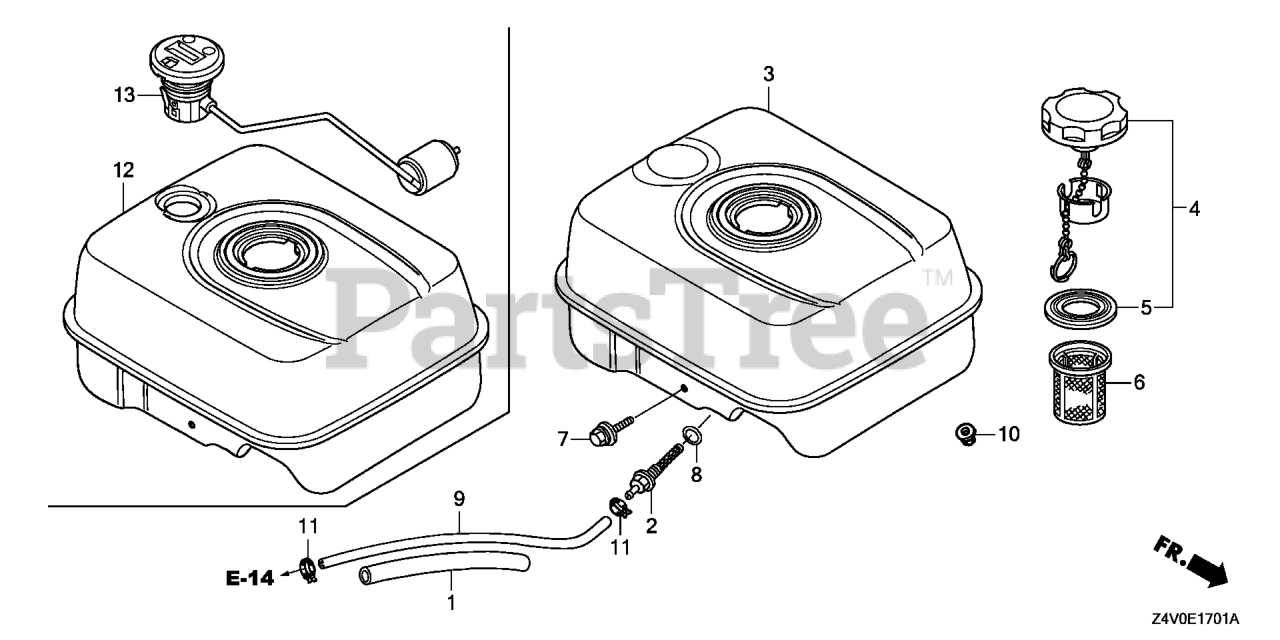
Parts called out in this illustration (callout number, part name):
1	RUBBER, SUPPORTER (107MM)
2	JOINT, FUEL TANK
3	TANK, FUEL *NH1* (BLACK)
4	CAP, FUEL FILLER
5	GASKET, FUEL FILLER CAP
6	FILTER, FUEL (FROM 1204807)
7	BOLT, FLANGE (6X34)
8	O-RING (14MM) (ARAI) Use up to Engine SN 2949254.
9	TUBE, FUEL (4.5X145)
10	NUT, FLANGE (6MM)
11	CLIP, TUBE (D8)
